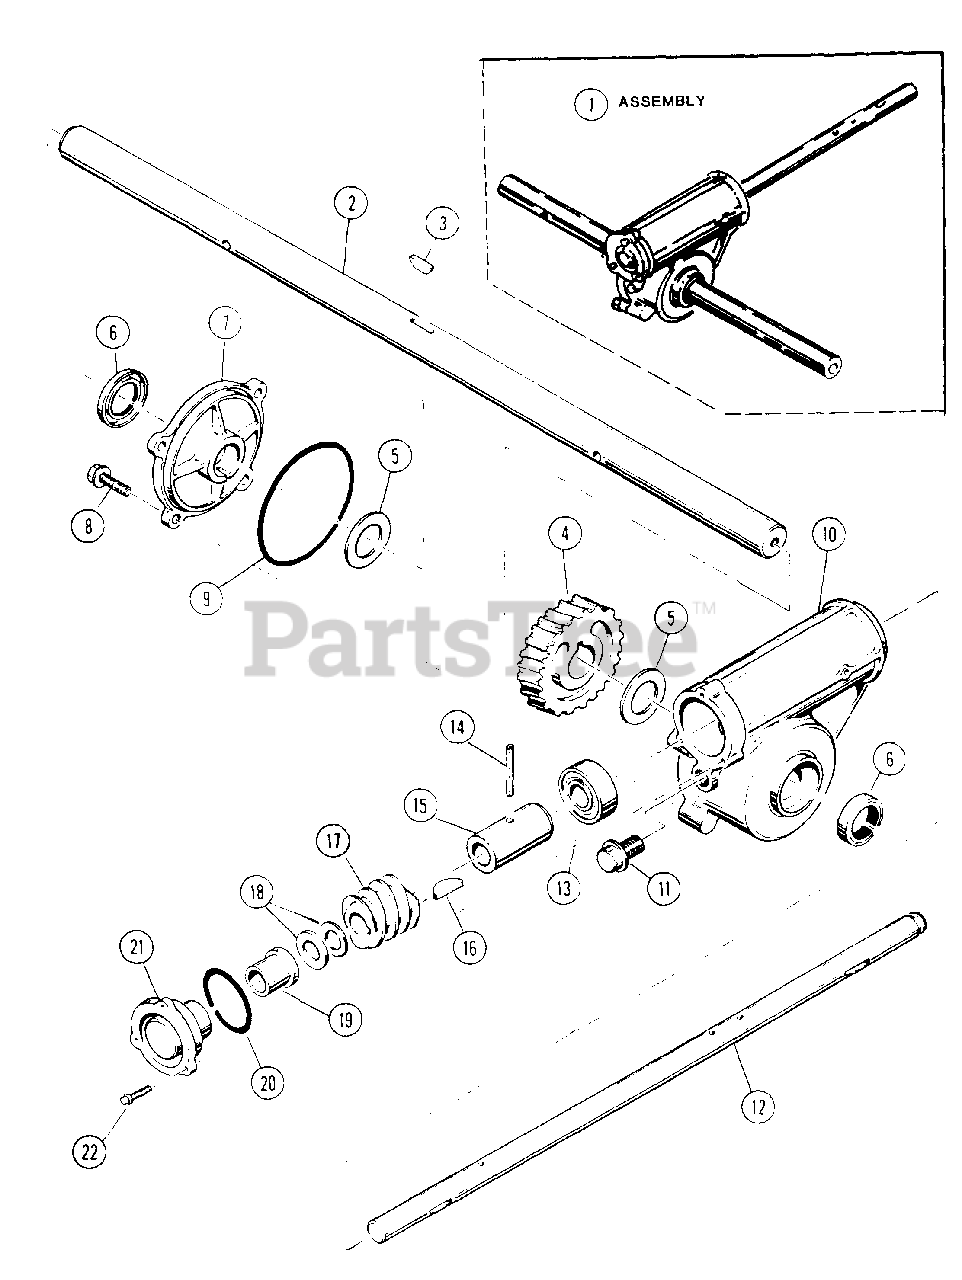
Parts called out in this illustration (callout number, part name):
1	ASSEMBLY, Gear Case
2	SHAFT, Auger
3	KEY, Woodruff
4	GEAR, Worm
5	WASHER, Thrust
6	SEAL, Oil
7	COVER, Gear Case
8	SCREW, 1/4-20x3/4 Self Tap
9	O-RING (Case Cover)
10	CASE, Gear
11	PLUG, Check (3/8x1/2 Self Tap Screw)
12	SHAFT, Impeller Fan
13	BEARING, Ball
14	PIN, 1/4 x 1-1/2" Roll
16	KEY, 3/16 x 7/8" Woodruff
17	GEAR, Rolled Worm
18	WASHER (Spacers)
19	BUSHING
20	O-RING (End Cap)
21	CAP, End
22	SCREW, 10-24x5/8 Self Tap
